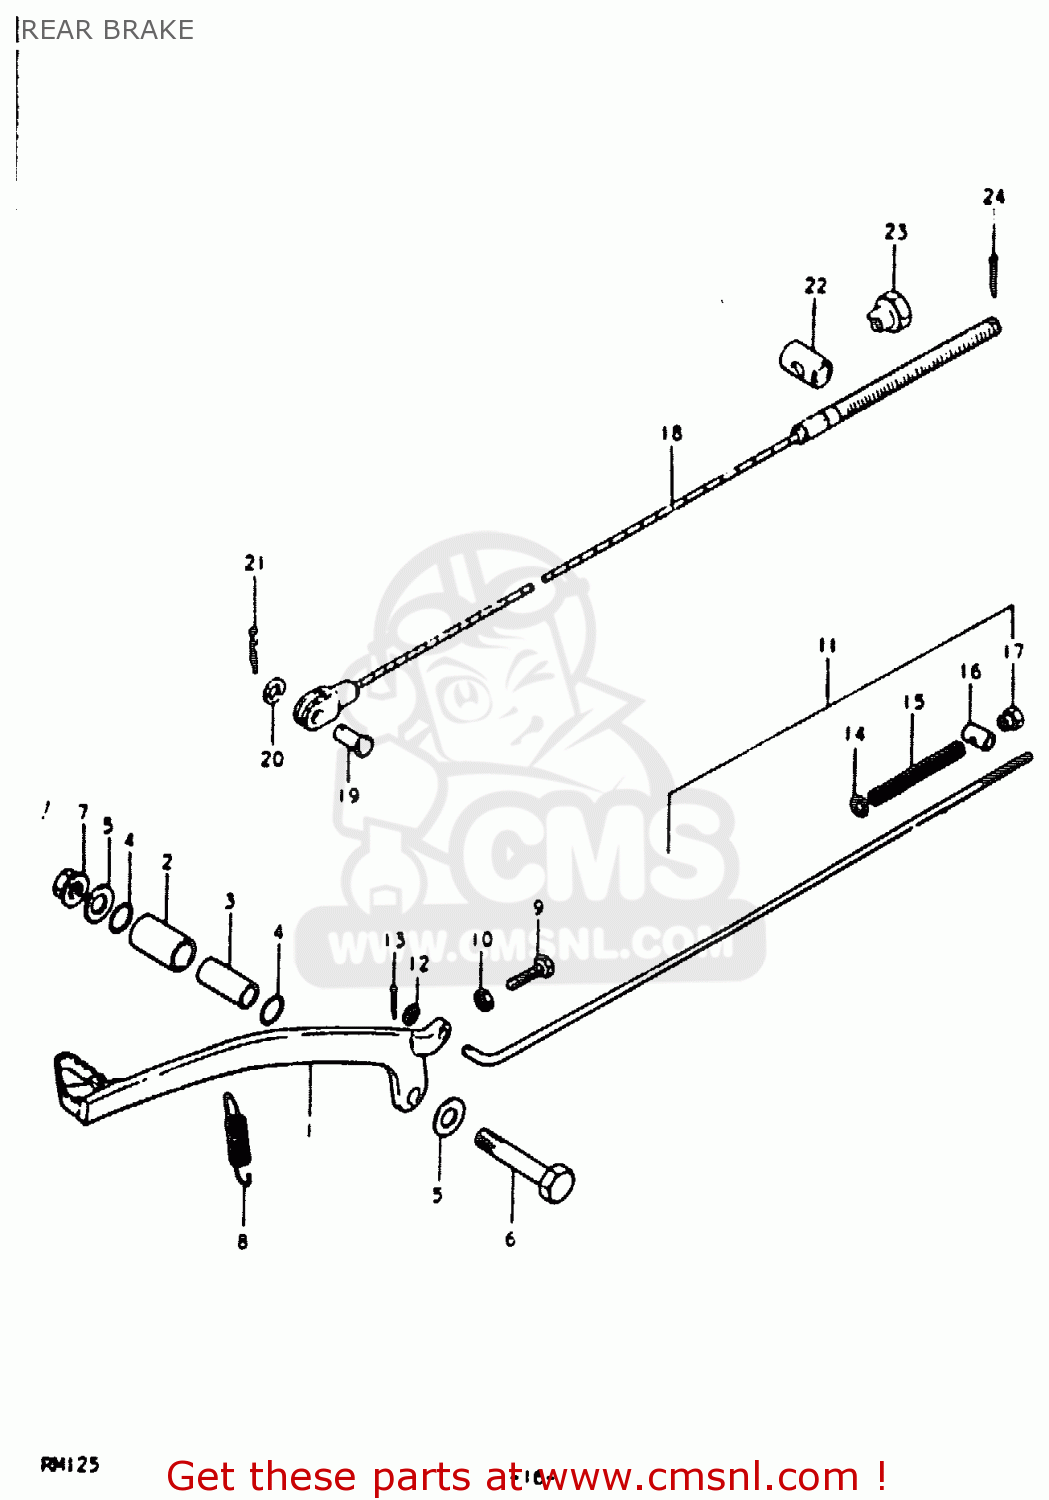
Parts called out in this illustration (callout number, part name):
1	PEDAL,BRAKE
2	BUSH
3	SPACER(10X14X32.2)
4	O RING(D:1.5,ID:13.8)
5	WASHER
6	BOLT
7	NUT
8	SPRING
9	BOLT(6X23)
10	NUT
18	CABLE,RR BRAKE
19	PIN(L:17.5)
20	WASHER
21	PIN 20X20
22	PIN
23	NUT
24	PIN
